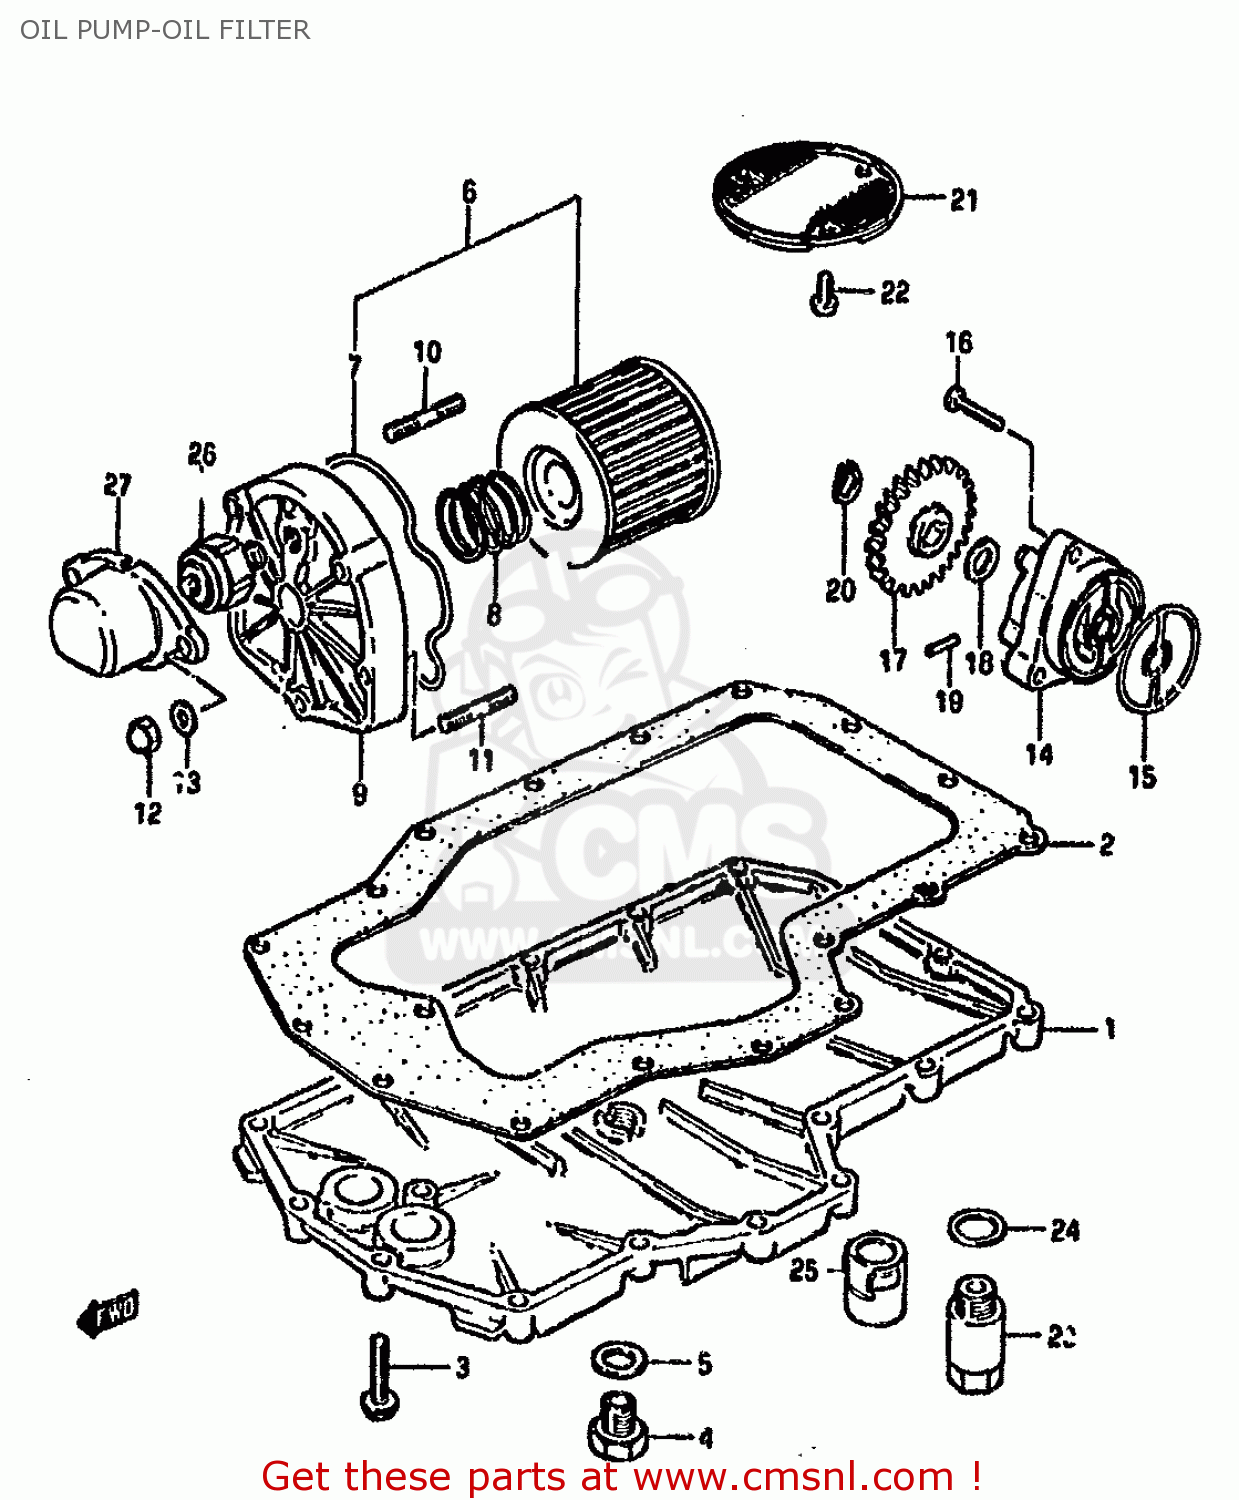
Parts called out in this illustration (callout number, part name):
1	PAN,OIL
2	GASKET,OIL PAN (MCA)
3	BOLT
4	PLUG
5	GASKET(14X19.2X2) (NAS)
6	ENGINE OIL FILTER SET
7	O RING,OIL FILTER CHAMBER CAP
8	SPRING
9	CAP,ENGINE OIL FILTER
10	STUD 6X30
11	STUD 6X25
12	NUT
13	WASHER
14	PUMP ASSEMBLY,OIL
15	O-RING,OIL PUMP
16	SCREW
17	GEAR,ENG OIL PUMP DRIVEN
18	SHIM
19	PIN(4X15.8)
20	CIRCLIP
21	STRAINER,ENGINE OIL
22	SCREW 6X12
23	VALVE ASSEMBLY,OIL RELIEF
24	WASHER
25	GUIDE, OIL REGULATOR
26	SWITCH ASSEMBLY
27	COVER,OIL PRESSURE SWITCH
